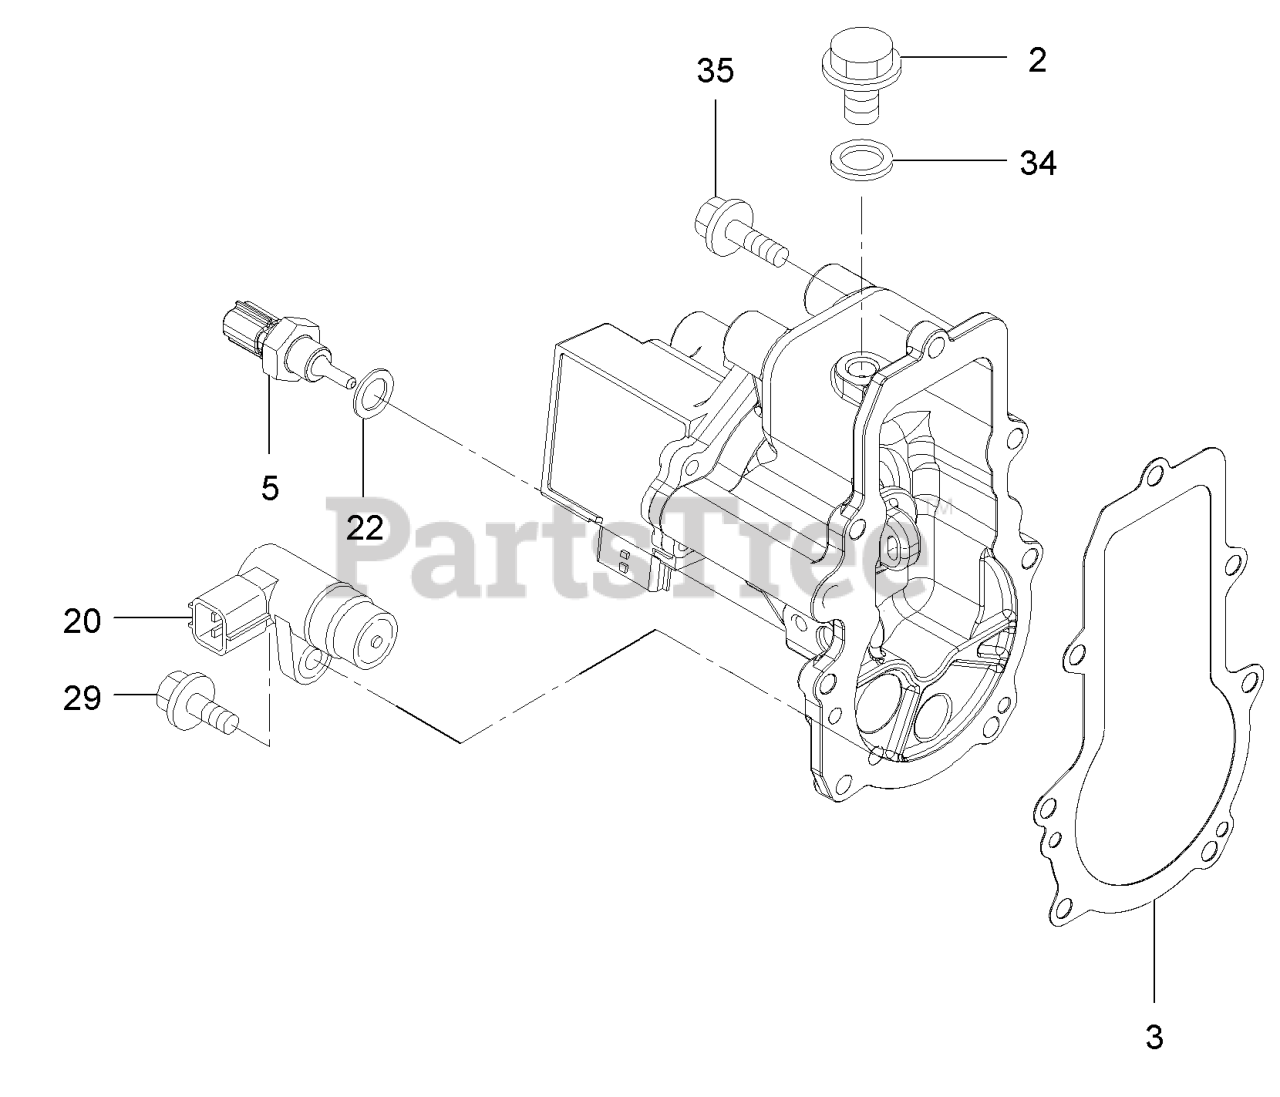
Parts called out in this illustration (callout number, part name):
5	Sensor-Oil Temp
22	Washer-Seal
34	Washer-Seal
